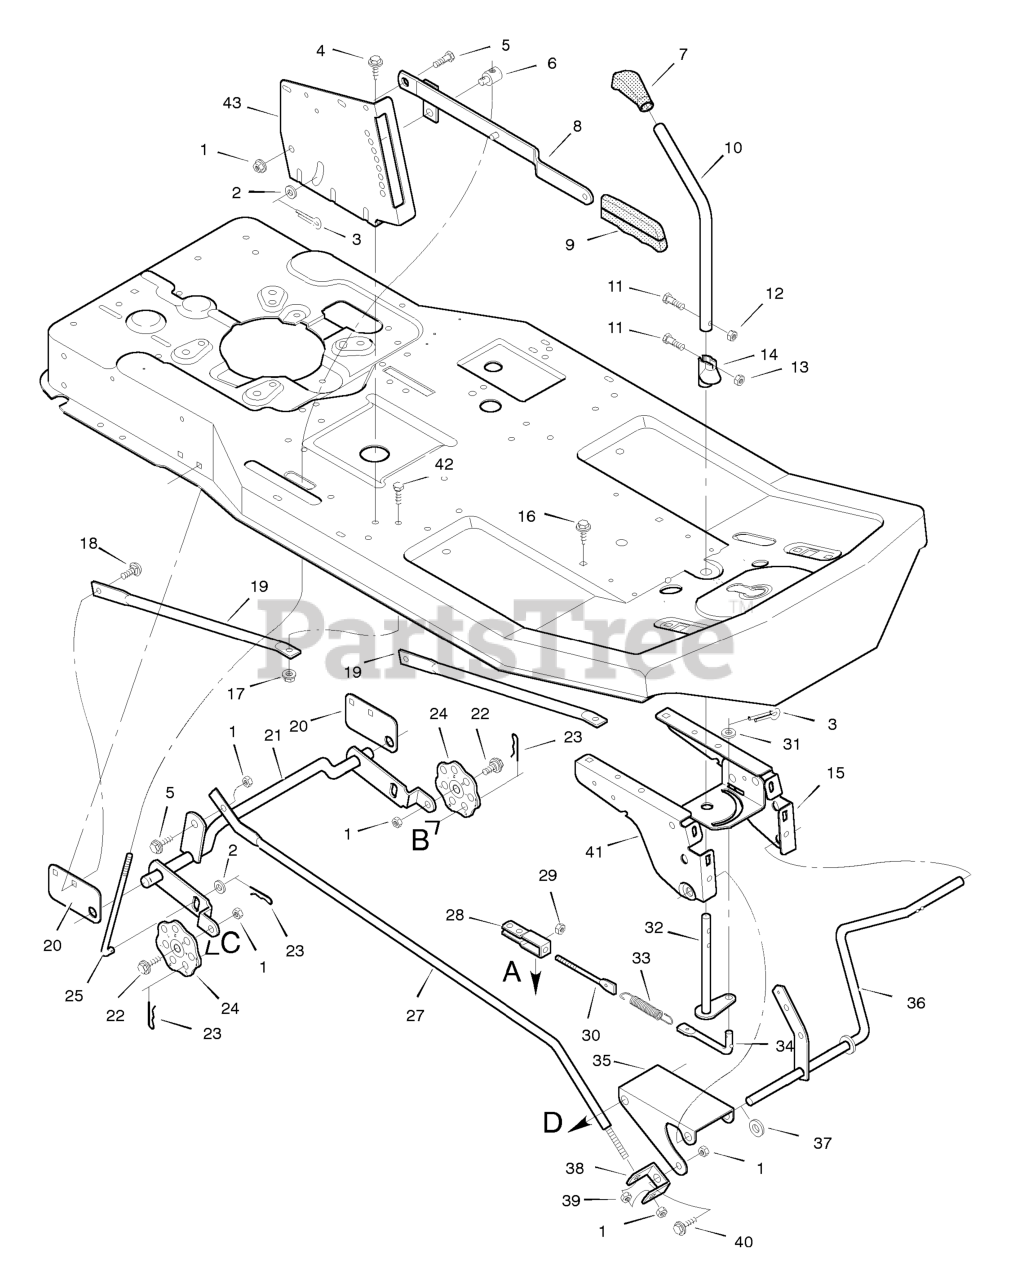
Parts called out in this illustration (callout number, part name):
1	Locknut, Flange
2	Washer
3	Pin, Cotter
5	Bolt, Shoulder
6	Nut, Adjusting
7	Grip, Blade Control
8	Lever Assembly, Lift
9	Grip, Lift Lever
10	Attachment, Clutch
11	Bolt, Hex
12	Locknut
13	Locknut, Flange
14	Cam, Blade Control
15	Plate, Left Suspension
17	Locknut, Flange
18	Bolt, Carriage
19	Strut, Frame
20	Plate, Mounting
21	Rod Assembly, Rear Suspension
22	Bolt, Shoulder
23	Pin, Hair
24	Plate, Adjusting
25	Rod, Lifter
27	Rod, Suspension
29	Nut, Hex
30	Link, Blade Drive
32	Rod and Arm Assembly
33	Spring, Extension
34	Link, Front Deck
35	Bracket, Front Suspension
36	Lever, Pedal
37	Washer
38	Clevis
39	Locknut, Hex
40	Bolt, Shoulder
41	Plate, Right Suspension
42	Bolt, Hex
43	Plate, Index
